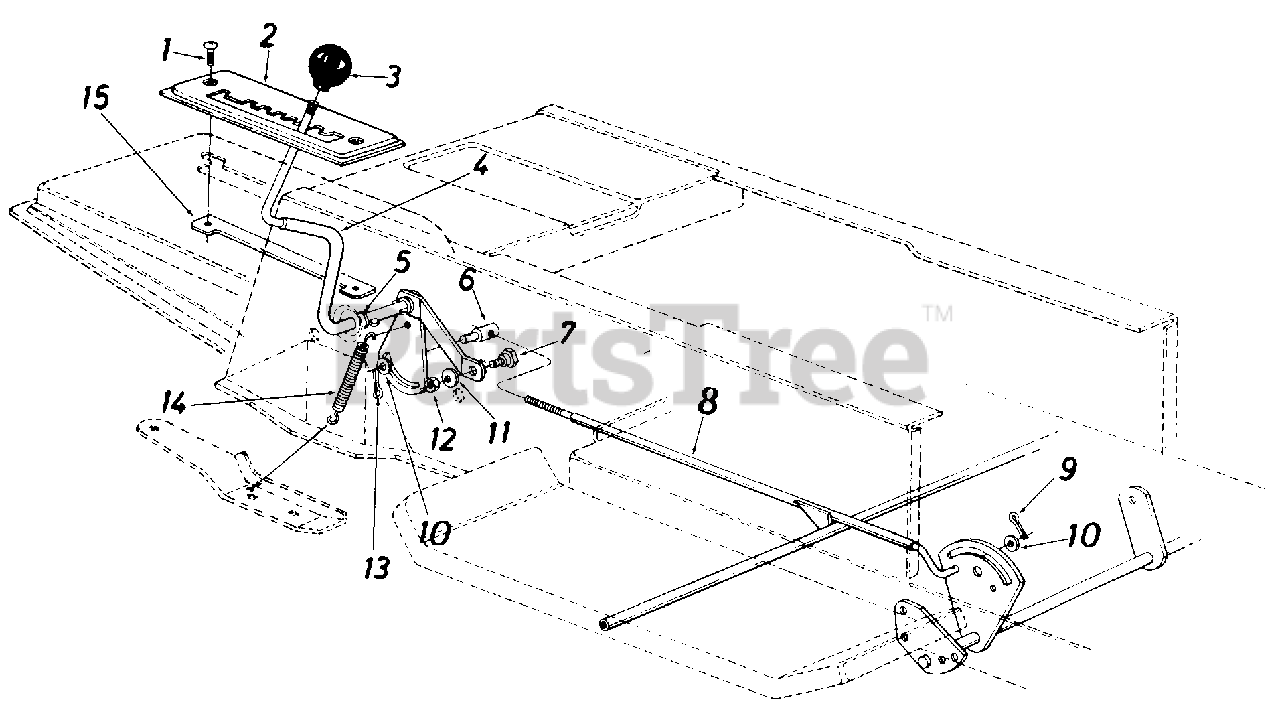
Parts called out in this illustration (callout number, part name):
1	Truss Mach. Scr. 1/4-20 x .75" Lg.
4	Speed Selector Cam Ass'y.
5	Flat Washer .53" I.D. x .93" O.D.
6	Ferrule 3/8-24 x .37" Dia.
7	Shoulder Bolt .435" Dia. x .160
8	Speed Control Rod Ass'y.
9	Cotter Pin 3/32" Dia. x .75" Lg.
10	Fl-Wash. .469" I.D. x .88" O.D.
11	L-Wash. 5/16" I.D.
12	Hex Nut 5/16-18 Thd.
13	Cotter Pin 3/32" Dia. x .75" Lg.
14	Spring .38" O.D. x 3.18" Lg.
15	Clamping Plate
